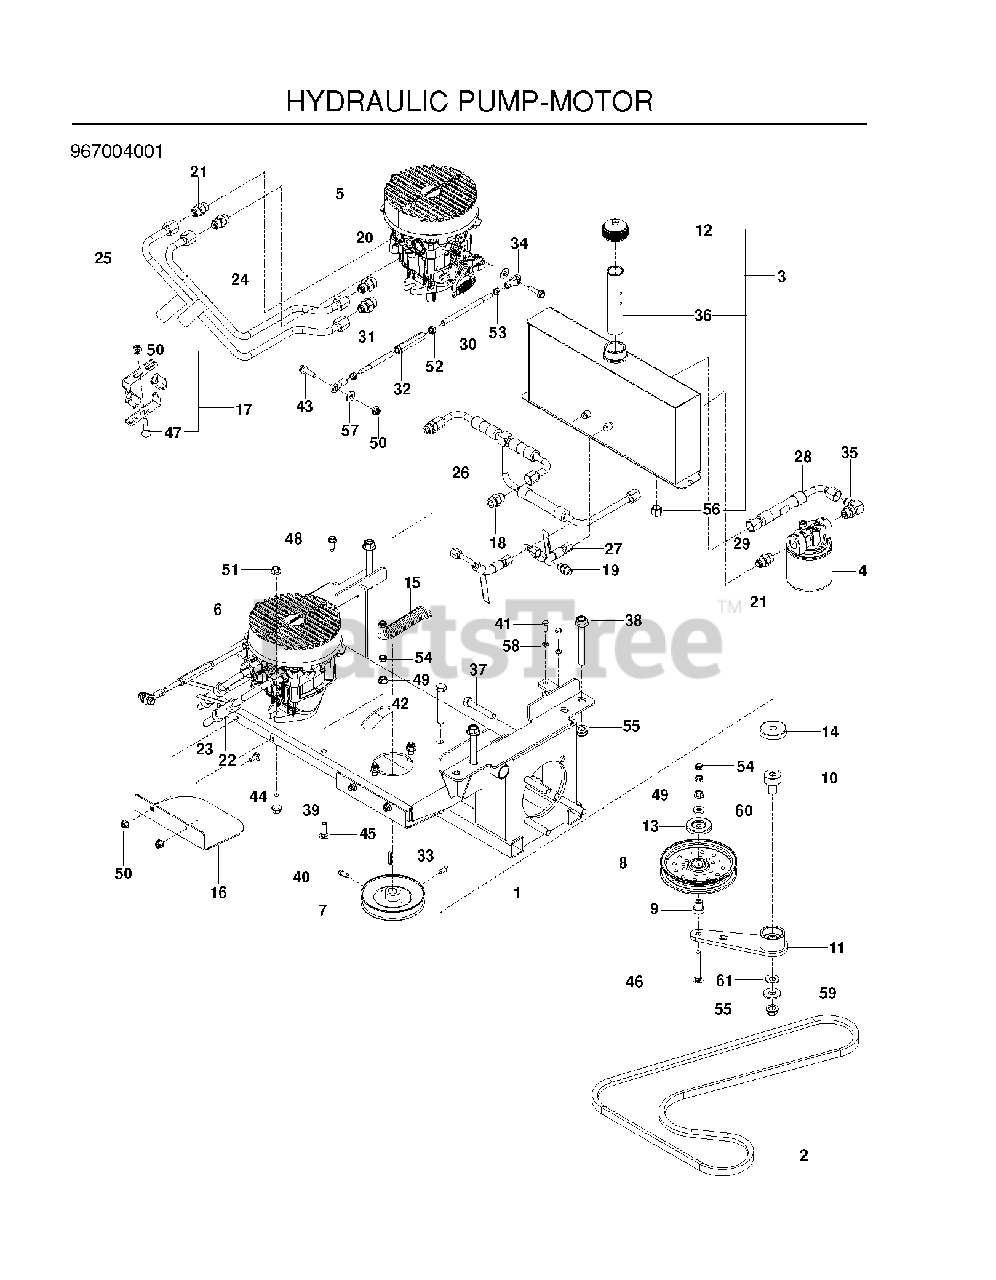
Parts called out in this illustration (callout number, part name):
1	FRAME, NYDR SUB, BLK
2	BELT, "B", 75.5"
3	ASSEMBLY, RESERVOIR, OIL
4	FILTER 25 MICRON
5	HG_PUMP, 12CC RT
6	HG_PUMP, 12CC LT
7	PULLEY, PUMP 15MM
8	IDLER, FLAT, 5.5"
9	PIVOT, IDLER
10	PIVOT, BEARING
11	ARM, IDLER, STEEL, W/BGS
12	CAP, HYDRAULIC
13	DUST SHIELD
14	SHIELD, DUST
15	SPRING, PUMP
16	SHIELD, PULLEY, BLK
17	ASM, VIB, HYDRO HOSE
18	FITTING, HYDRO
19	STRAIGHT FITG
20	CONNECTOR, STRAIGHT
21	FITTING, STRAIGHT F6400-8-8-0
22	LINE, RT A
23	LINE, RT B
24	LINE, LT A
25	LINE, LT B
26	LINE, CHARGE
27	LINE, CASE
28	LINE, SUCTION
29	FILTER HEAD
30	LINKAGE, CONTROL, RR
31	LINKAGE, CONTROL, FT
32	TURNBUCKLE, 3/8
33	KEY 5 MM SQ X 25 MM
34	BALL JOINT, RIGHT HANDED
35	ELBOW, 90 DEGREE
36	TUBE, ANTI-SPLASH
37	HCS 1/2C X 2 3/4
38	HHFS 1/2-13 X 4.0 GD8 ZD
39	HHFS 3/8-16 X 1.25 GD 5
40	SCREW 5/16C X 5/8 SQ HEAD
41	HCS 1/4C X 5/8
42	HCS 1/2C X 3 1/4
43	HHFS 5/16-18 X 1.25 TPBLT GD 5
44	BOLT 5/16C X 3/4" CARRIAGE
45	RHSNB 3/8-16 X 1-1/4
46	RHSNB 3/8-16 X 2.75
47	RHSNB 5/16-18 X 1-1/2 GR 5 ZD
48	RP BLT 5/16-18 X 1 THRD FORM D
49	NUT 3/8C WHIZ
50	5/16-18 NYLOC FLANGE NUT
51	NUT 3/8-16 HEX FLG NYLOC ZD
52	NUT 3/8-24 JAM
54	NUT HEX 3/8-16 NYLON, THIN
55	NUT, 1/2-13 HEX FLG NYLOC ZD
56	NUT 9/16-18 JIC CAP
57	WASHER 5/16 FLAT
58	LOCKWASHER 1/4"
59	WASH USS FLAT 1/2
60	WASHER, 3/8 THICK
61	CONTACT BELLSPR 1/2
